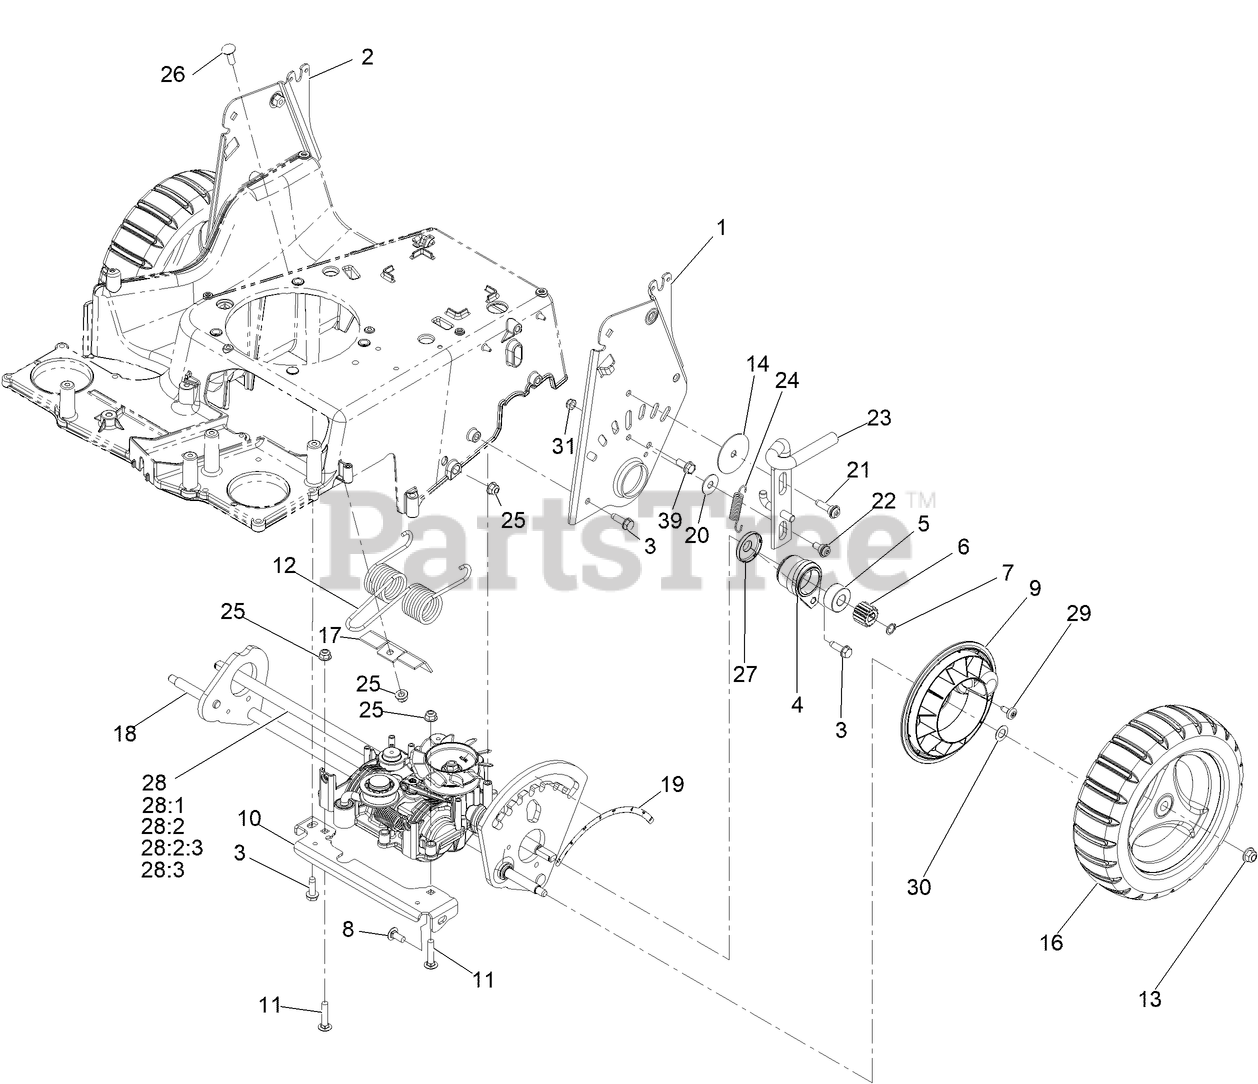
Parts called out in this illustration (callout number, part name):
1	HOC Plate Assembly
2	HOC Plate Assembly
3	SCREW-THD ROLL, HWH
4	Bearing Retainer ASM
5	BEARING-BALL, CUSTOM
6	GEAR-PINION, 15T
7	RING-RETAINING
8	SCREW-CARR
9	Cover-Wheel
10	Bracket-Transmission, Front
11	BOLT-CARR
12	SPRING-TORSION
13	NUT-HF, NI
14	WASHER-PLAIN
16	WHEEL ASM, 10.5 W/GEAR
17	BRACKET
18	REAR AXLE ASM
19	DECAL-HOC, REAR
21	SCREW-SHOULDER, BHTF
22	BOLT-SHOULDER
23	LOCK-HEIGHT, ADJ
24	Wheel ASM, 10.5 W/Gear
25	NUT-HF, NI
26	BOLT-CARR
27	COVER-BEARING
28	TRANSMISSION-MV702
28:1	Pulley & Fan Repair Kit
28:2	Idler Pulley Repair Kit
28:2:3	Spring-Tension, Belt
28:3	Clutch Lever Repair Kit
29	SCREW-SHOULDER
30	WASHER-PLAIN
31	NUT-LOCK, NI
